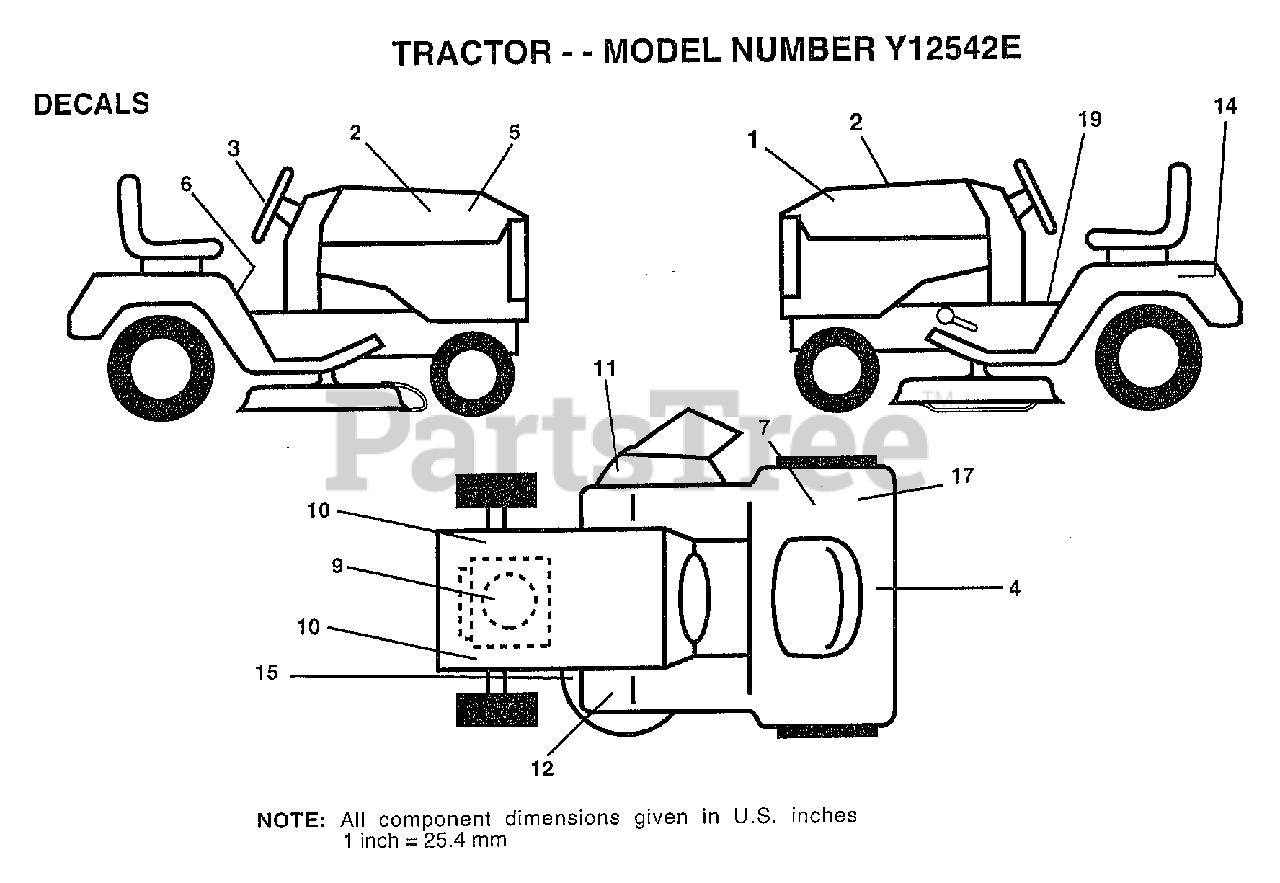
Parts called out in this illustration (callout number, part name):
1	DECAL.HD.LH.
2	DECAL.PANEL.SIDE
3	DECAL.INS.WHL.STG
5	DECAL.HD.RH.
6	DECAL.READ.O.MANU
7	DECAL.EURO.ST.CE.
9	DECAL, HP ENGINE
10	"DECAL CHASSIS,HOT"
11	DECAL.DANGER.CUTF
12	DECAL-BRAKE/CLUTC
14	DECAL.BATRY.3-3908
15	DECAL
19	DECAL BRAK PARK
